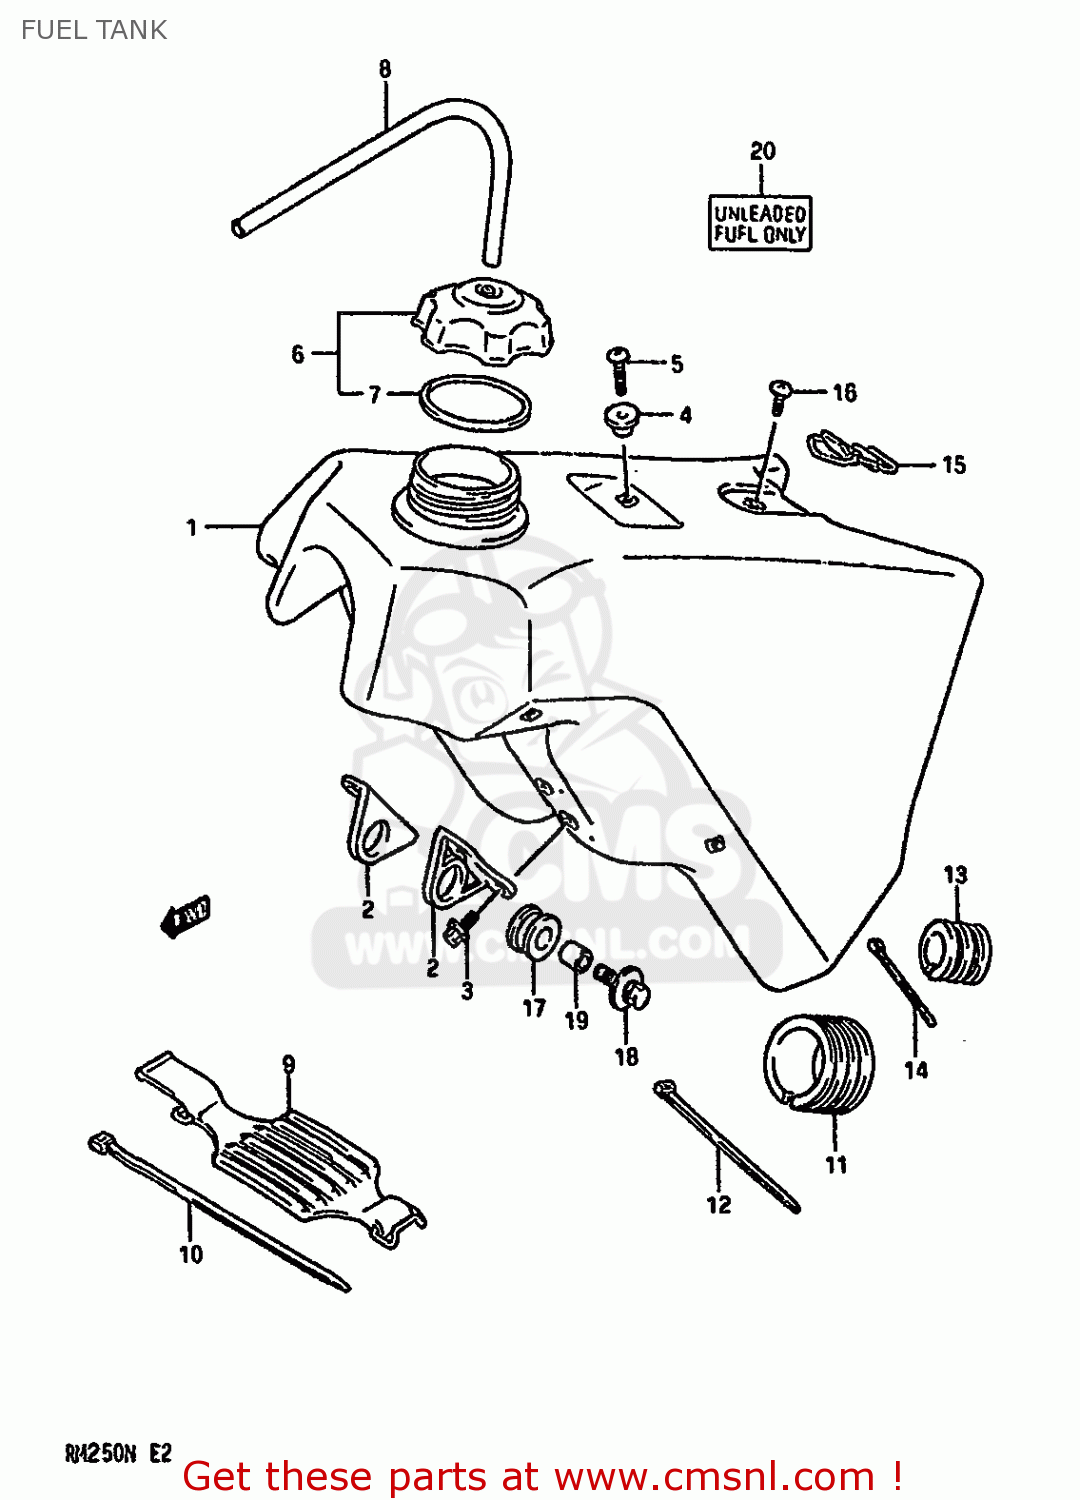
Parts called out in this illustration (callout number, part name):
1	TANK SET,FUEL
2	BRACKET,FUEL TANK FR
3	BOLT
4	HOOK,SEAT,FRONT
5	SCREW
6	CAP SET,FUEL TANK
7	GASKET,CAP (NAS)
8	HOSE(5X9X600)
9	CUSHION,FUEL TANK NO.1
10	CLAMP
11	CUSHION,FUEL TANK NO.2
12	CLAMP(L:300)
13	CUSHION,FUEL TANK NO.1
14	CLAMP(L:145)
15	BAND,FUEL TANK RR
16	SCREW
17	CUSHION
18	BOLT(8X30)
19	SPACER (8.8X12X13.5)
20	LABEL,UNLEADED FUEL
